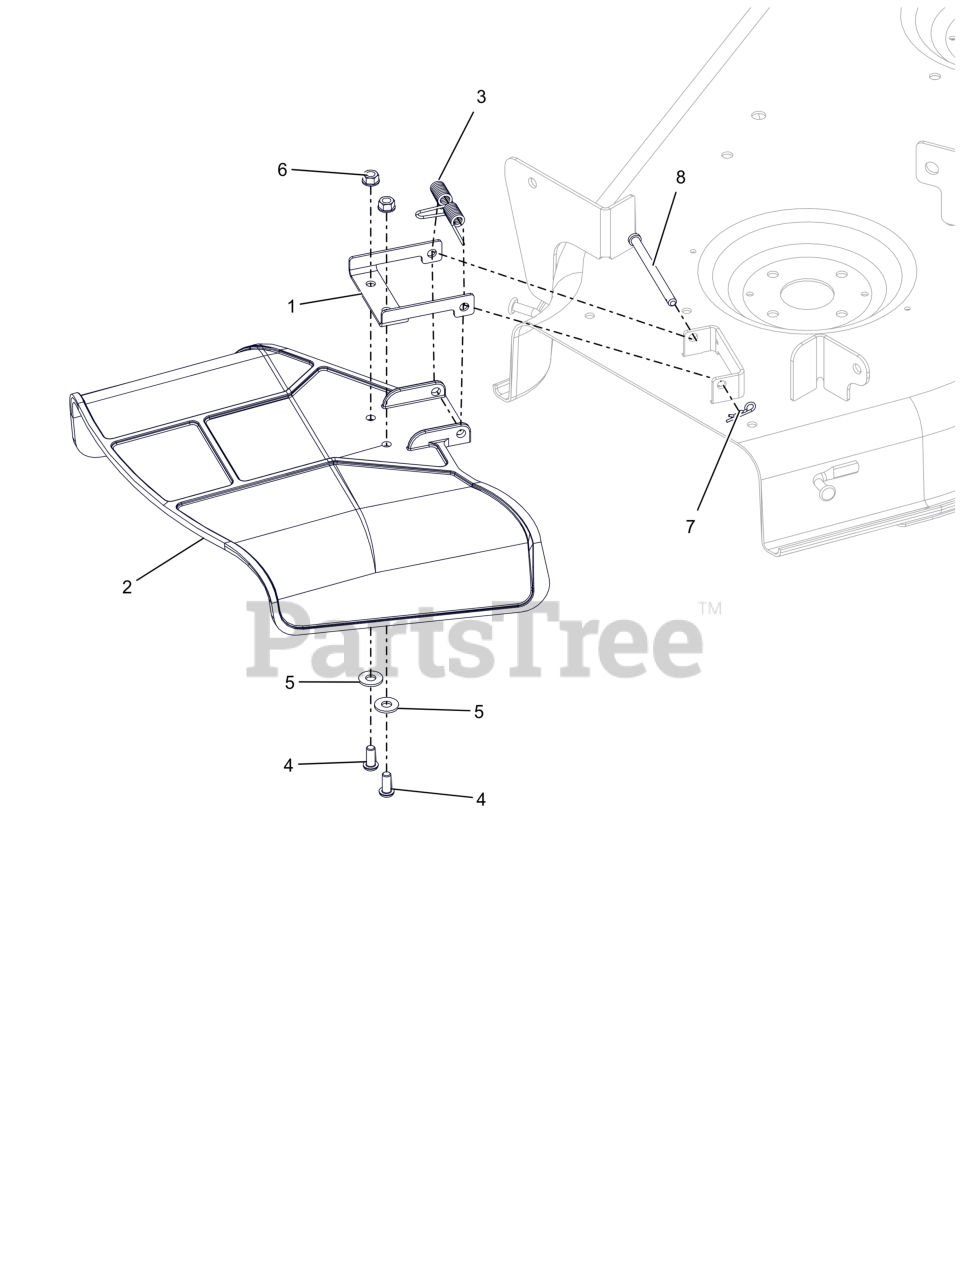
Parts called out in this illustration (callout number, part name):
1	CHUTE REINFORCEMENT
2	CHUTE, SIDE DISCHARGE
3	SPRING, TORSION
4	SCR-SKH .31-18X.75 BTNHD YWZC
5	WSHR,FLT .375X.875X.083 ZCC
6	NUT,LK-CTR-FLG .31-18 GF ZCC
7	PIN, HAIR #213 .08X1.19 ZCC
8	PIN, 5/16 X 3.88"
